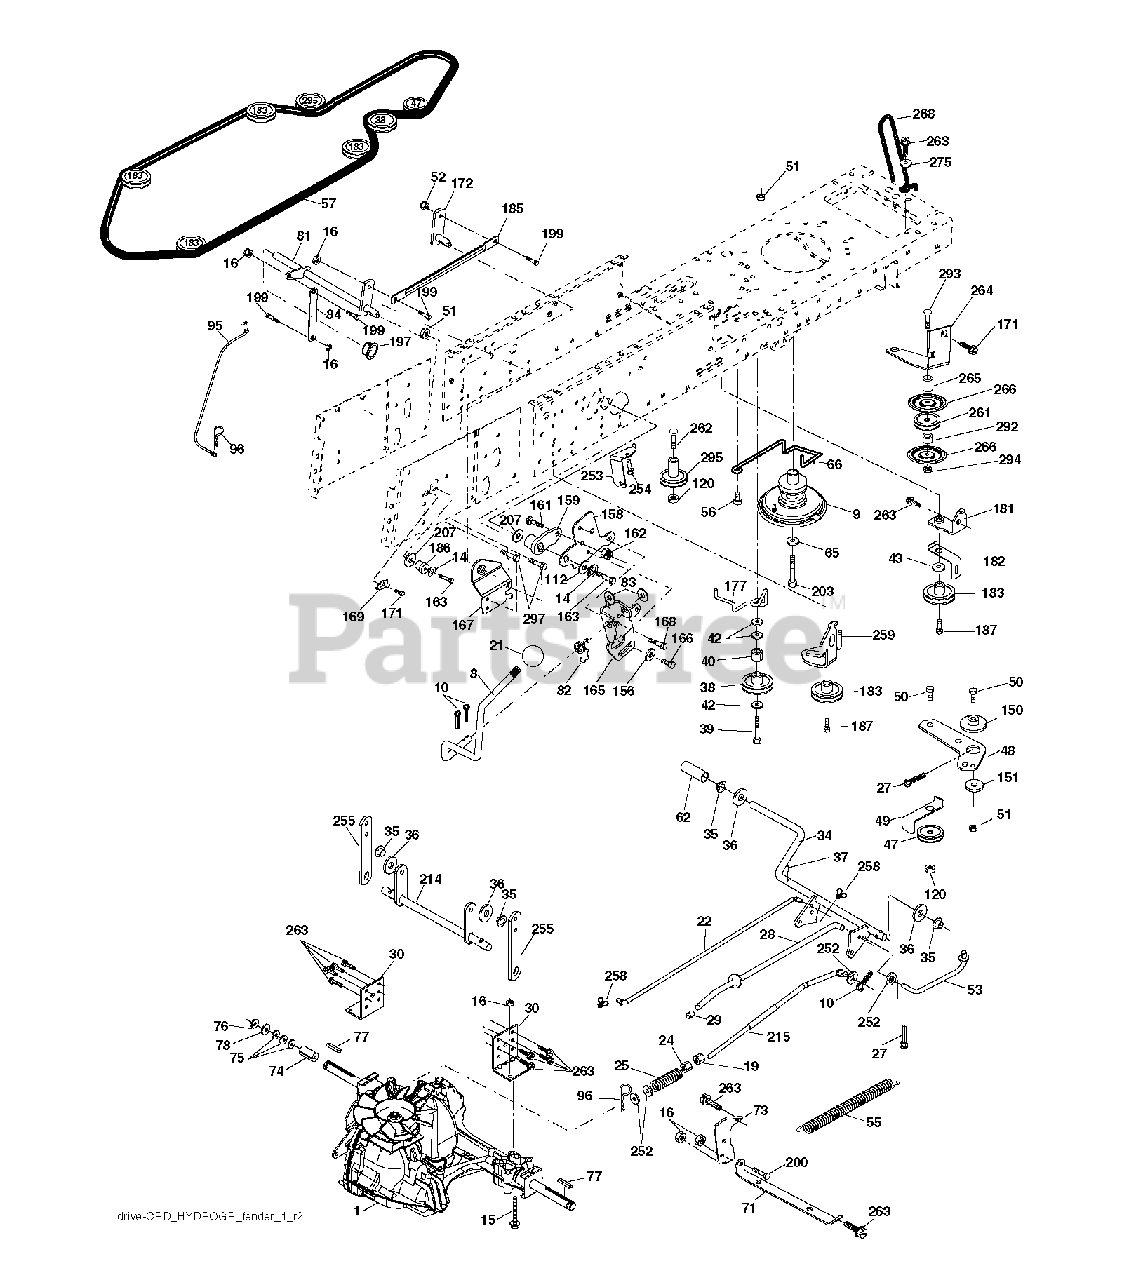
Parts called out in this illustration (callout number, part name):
8	ROD SHIFT FENDER ADJUST LT
10	PIN COTTER
14	LOCKWASHER
15	BOLT HEX 5/16-18 GR 5
16	NUT.71038.31-18.HEX.NYLOCK
19	NUT
21	PISTOL KNOB
24	NUT
27	COTTER PIN
28	ROD, PARKING BRAKE
29	PLUNGER CAP
30	BRKT, TRNSXLE MNT 20"
34	SHAFT, FOOT PEDAL
35	BEARING.NYLON
36	WASHER LT
37	DRIVE PIN
38	PULLEY.FLAT
42	WASHER
47	IDLER PULLEY
48	BELLCRANK, CLUTCH
49	RETAIN BELT
50	BOLT.3/8-16X1.50
51	LOCKNUT
52	LOCKNUT
53	LINK.CLUTCH.7.66.2005
55	SPRING, RETURN LT
56	SCREW.3/8-16
62	PEDAL COVER T
65	LOCKWASHER
66	KEEPER BELT ENGINE
71	STRAP TORQUE LH HYDRO
73	STRAP TORQUE RH HYDRO
74	SPACER AXLE
76	E-RING LT
77	SQUARE KEY
81	SHAFT ASSY
82	SHIFT SPRING
83	WASHER
96	RETAINER M
112	WASHER LT
120	NUT LOCK FLG 3/8-16 UNC
150	BUSHING.BELLCRANK.GRD.DR
151	WASHER 12/32X2X10GA
156	WASHER.SRRTD.5/16
158	BRACKET
159	HUB.SHIFT
161	BOLT
162	NUT.CROWNLOCK.1/4
165	RP BRACKET
167	BRACKET
168	BOLT.SHOULDER.5/16-18X
169	PLATE.FASTENING.CROSS.SHAFT
183	PULLEY.V-IDLER.
187	BOLT.5/16-18X1.25
197	NYLINER SNAP 5/8" ID
199	BOLT SHOULDER 5/16-18 UNC
200	BOLT
207	WASHER NYL
254	SCREW 3/8-16X1
258	CLIP RETAINER
261	FLAT IDLER PULLEY
263	SCREW, 3/8-16X3/4
275	WASHER
294	NUT, HEX 3/8-16
295	PULLEY IDLER COMPOSITE
297	SCREW LT.3/8-46X5/8
